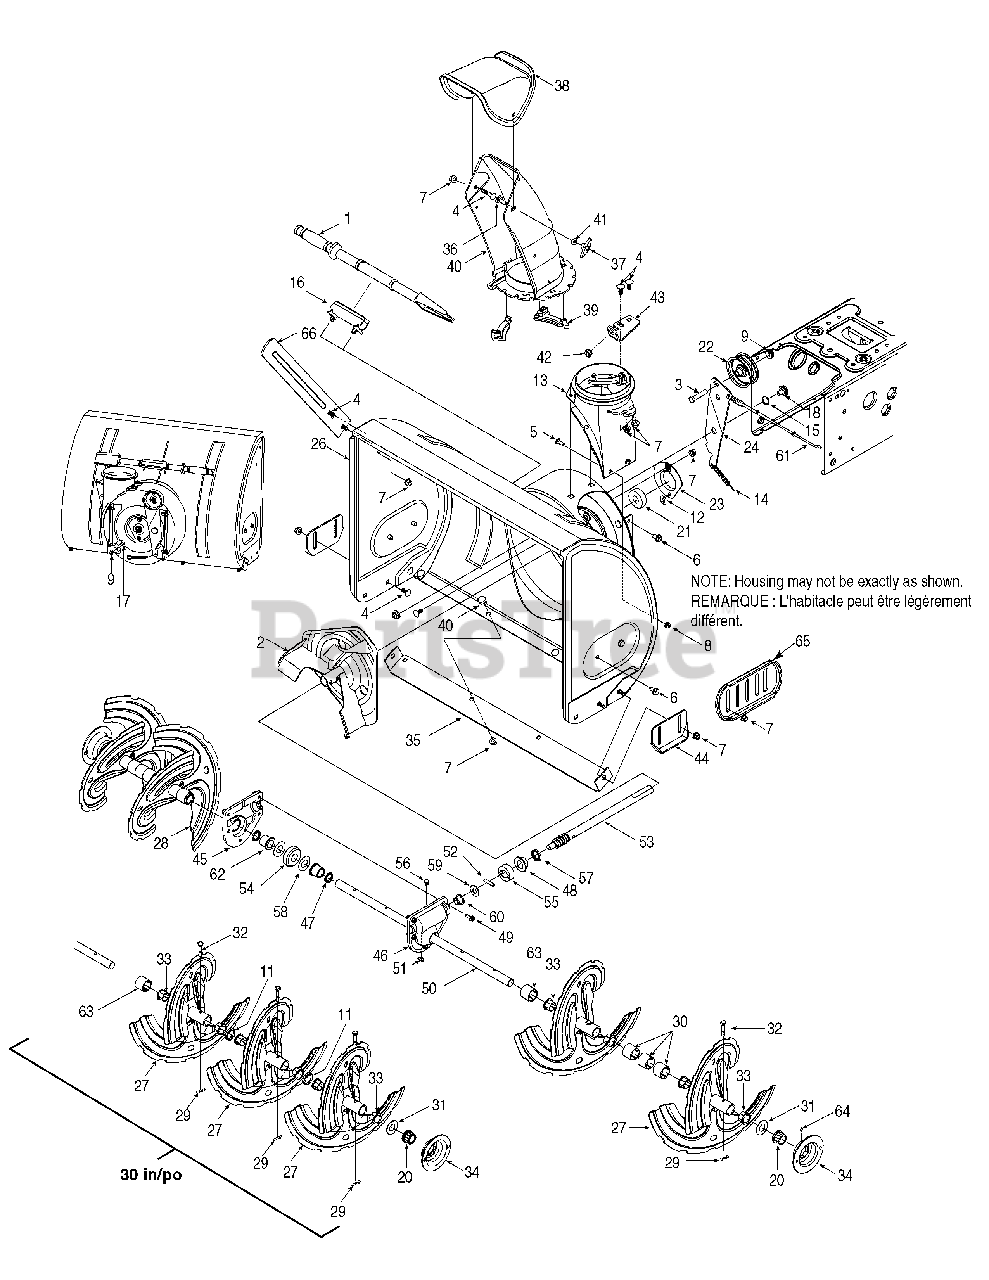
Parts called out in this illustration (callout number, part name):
1	Clean-Out Tool
3	Hex Screw 3/8-16 x 1.75
4	Carriage Bolt 5/16-18 x .75 Gr. 1
5	Carriage Screw 1/4-20 x .75 Gr. 5
6	Hex Wash HD AB Tap Scr 5/16-18 x .625
7	Flange Locknut 5/16-18 Gr. F Nylon
8	Hex L-Flanged Nut 1/4-20 Gr. F Nylon
9	Hex L-Flanged Nut 3/8-16 Gr. F Nylon
10	Internal Cotter Pin
11	Spacer 1.25 x .75 x 3/16" Lg.
12	Push-on Nut .25 dia.
13	Chute Adapter
14	Extension Spring
15	Wave Washer .660 ID x .88 OD x .010
16	Cleanout Tool Mount
17	Shld. Scr. .500 Dia. x .335" Lg.
18	Shoulder Scr .625 Dia x .170
19	Shear Pin .25 x 1.5 Gr. 2
20	Hex. Flange Brg. .751" I.D.
21	Self-aligning bearing
22	Flat Idler Pulley 2.75" OD
23	Bearing Housing 1.85 ID
25	Gearbox 26"
25	Gearbox 30"
29	Bow Tie Cotter Pin
30	Spacers for 26" Auger Housing (2)
31	Flat Washer .760 ID x 1.49 OD
32	Shear Pin .25 x 1.5 Gr. 2
33	Flange Bushing
36	Carriage Bolt 5/16-18 x 1.0
37	Handle Knob Assembly
38	Upper Chute
39	Chute Flange Keeper
40	Lower Chute
41	Flat Washer .349 ID x .879 OD x .063
42	Plastic Bushing .380 ID
45	RH Reduced Auger Housing
46	LH Reduced Auger Housing
47	Oil Seal 3/4 ID
48	Flange Bearing .75 ID x 1.00 OD x .50
49	Thd Forming Scr. 1/4-20 x .75
50	Auger Axle 26"
50	Auger Axle 30"
51	Hi Pro Key 3/16 x 5/8
52	Dowel Pin .25 OD x 1.2
53	Worm Shaft .75 OD
54	Worm Gear 20T
55	Thrust Collar
56	Plug, 1/4 x .437
57	Oil Seal .75 x 1 x .131
58	Flat Washer .76 ID x 1.5 OD x .03
59	Fl. Washer .510 x 1.120 x .060
60	Flange Bearing .75 ID x 1.0 OD x .925
61	Auger Clutch Cable (w/"Z" fitting)
62	Flange Bearing.75 ID x 1.0 OD x .975
63	Spacer 1.25 x .75 x 1.00
64	Grease Fitting (optional)
